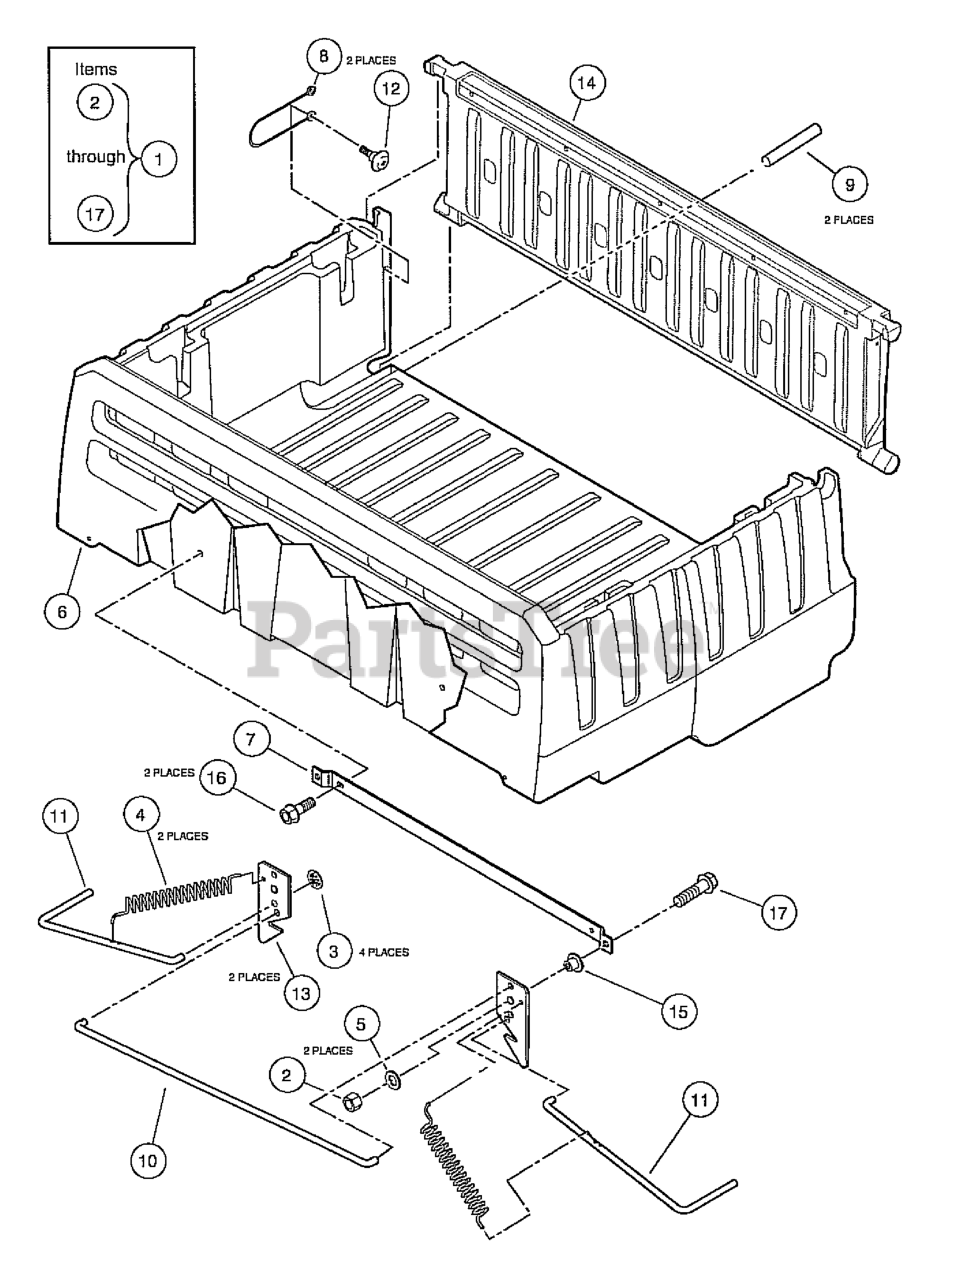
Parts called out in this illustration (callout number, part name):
1	BED ASM - H2
2	LOCKNUT, DIMPLED
3	PUSHNUT, 3/8
4	EXENSION SPRING LATCH CA
5	Washer, 3/8 Flat Type A
6	Bed, Cargo
7	Support, Latch Link
8	LANYARD, TAILGATE
10	Rod, Long Link
11	Rod, Bed Lift, Short Bent
12	BOLT LANYARD
13	Catch, Tilt Bed
14	TAILGATE, HUSQVARNA
15	Bearing, Bronze, 1/2 x 9/32
17	SCREW, CAP, HEX HD 3/8-16X1.00
